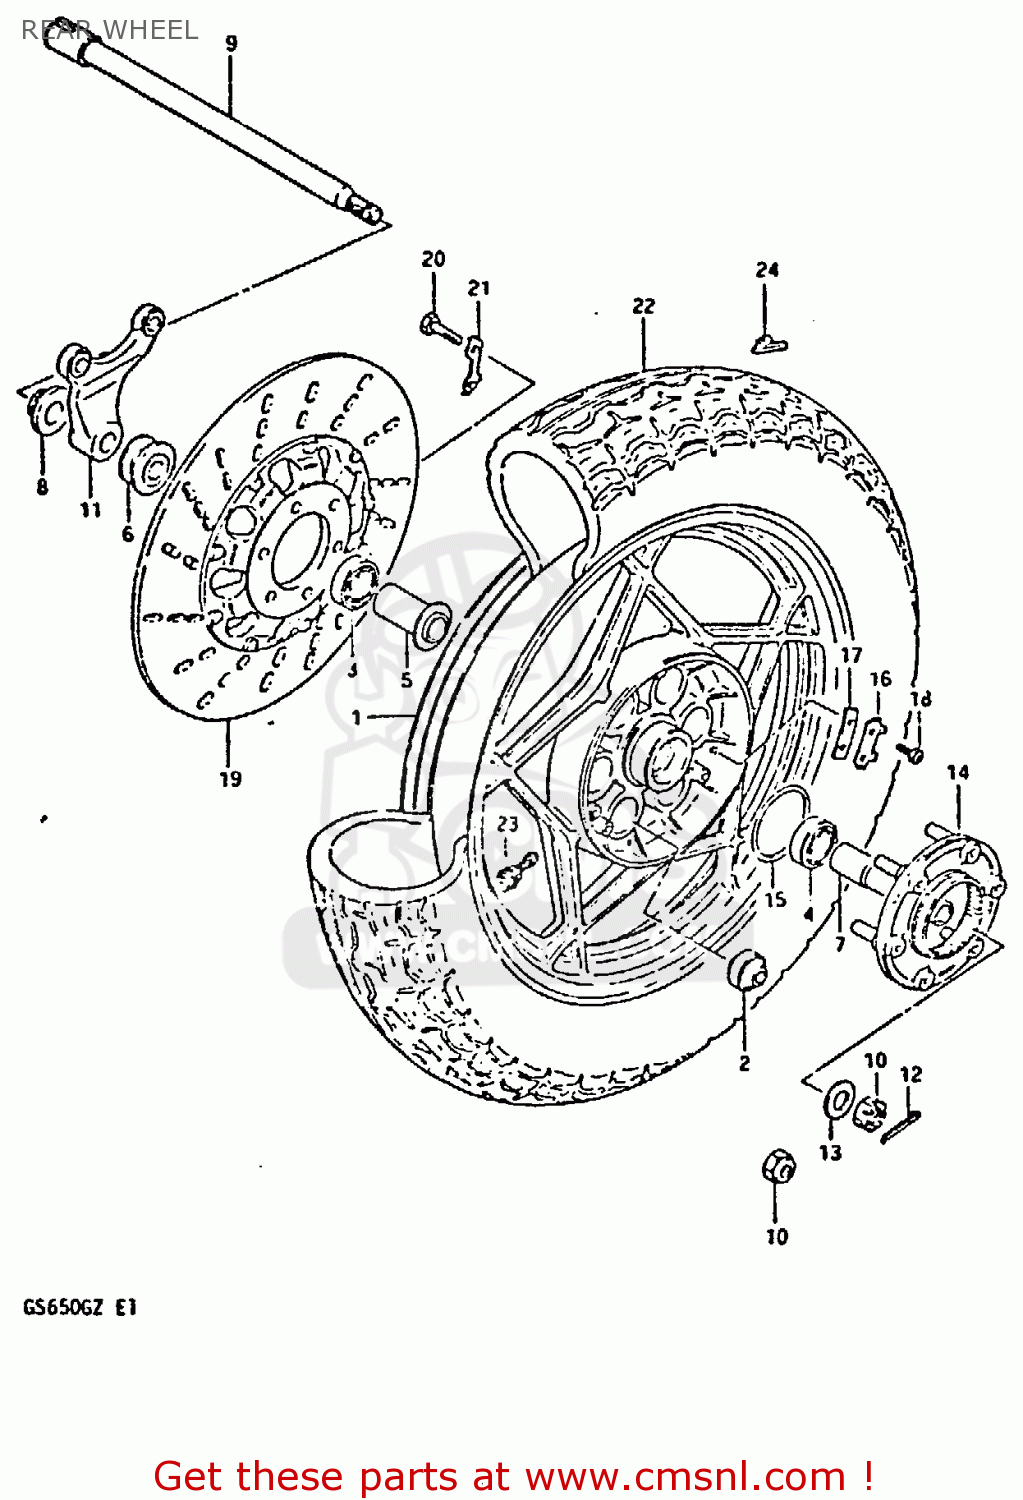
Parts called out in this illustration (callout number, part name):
1	WHEEL SET,REAR
2	BUSH
3	BEARING
4	BEARING
5	SPACER,REAR HUB BEARING
6	SPACER,REAR AXLE
7	SPACER,REAR AXLE,LEFT
8	SPACER,REAR AXLE,RIGHT
9	AXLE,REAR
10	NUT
11	BRACKET,REAR CALIPER
12	PIN,COTTER
13	WASHER(16.5X36X3.2)
14	JOINT ASSEMBLY,REAR HUB DRUM
15	O RING(D:2.1,ID:65)
16	WASHER (T:1.0)
17	WASHER,THRUST(T:1.6)
18	SCREW
19	DISC,REAR BRAKE
20	BOLT(8X28)
21	WASHER
22	TIRE
23	VALVE ASSEMBLY,WHEEL RIM,J
24	BALANCER,WHEEL
